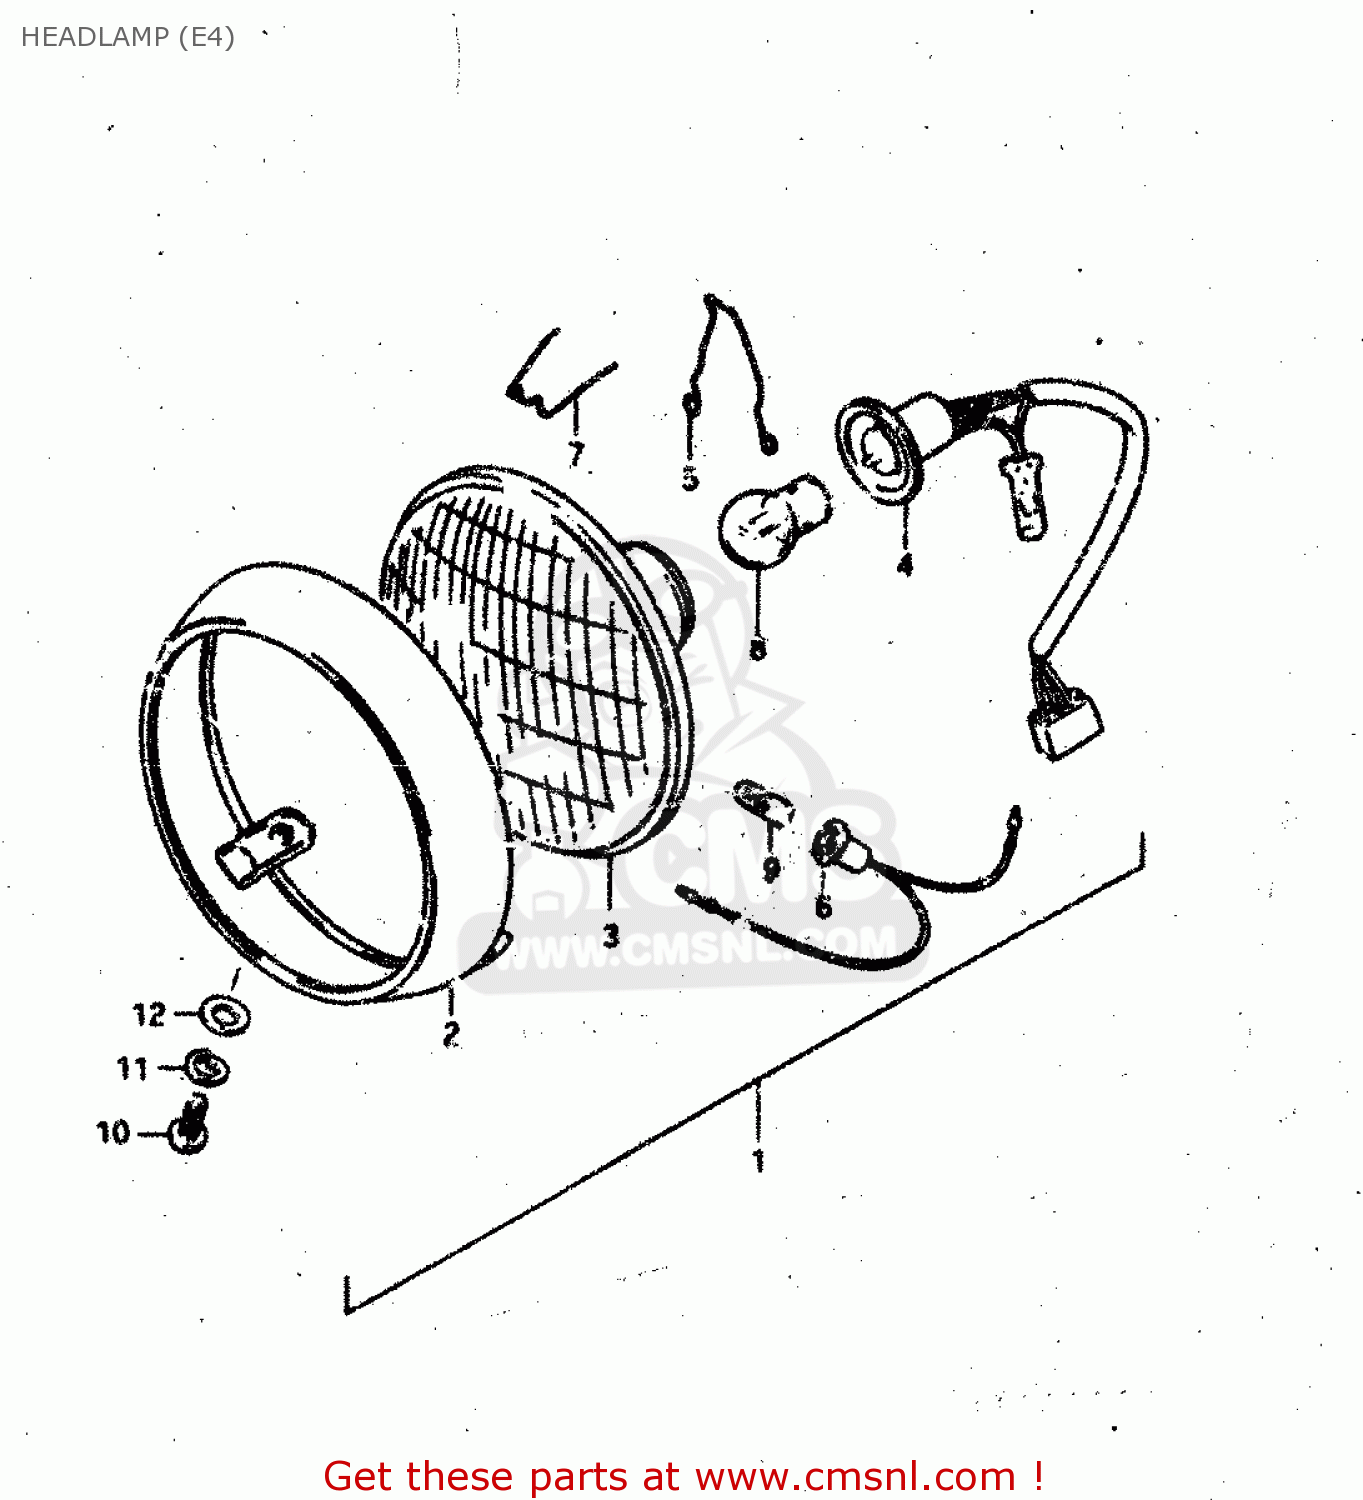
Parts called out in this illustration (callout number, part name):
1	HEADLAMP ASSY
2	RIM
3	UNIT
4	SOCKET
5	CLAMP,HEADLAMP
6	SOCKET
7	SPRING
8	BULB (6V,25/25W)
9	BULB (6V,4W)
10	SCREW
11	LOCK WASHER
12	WASHER
